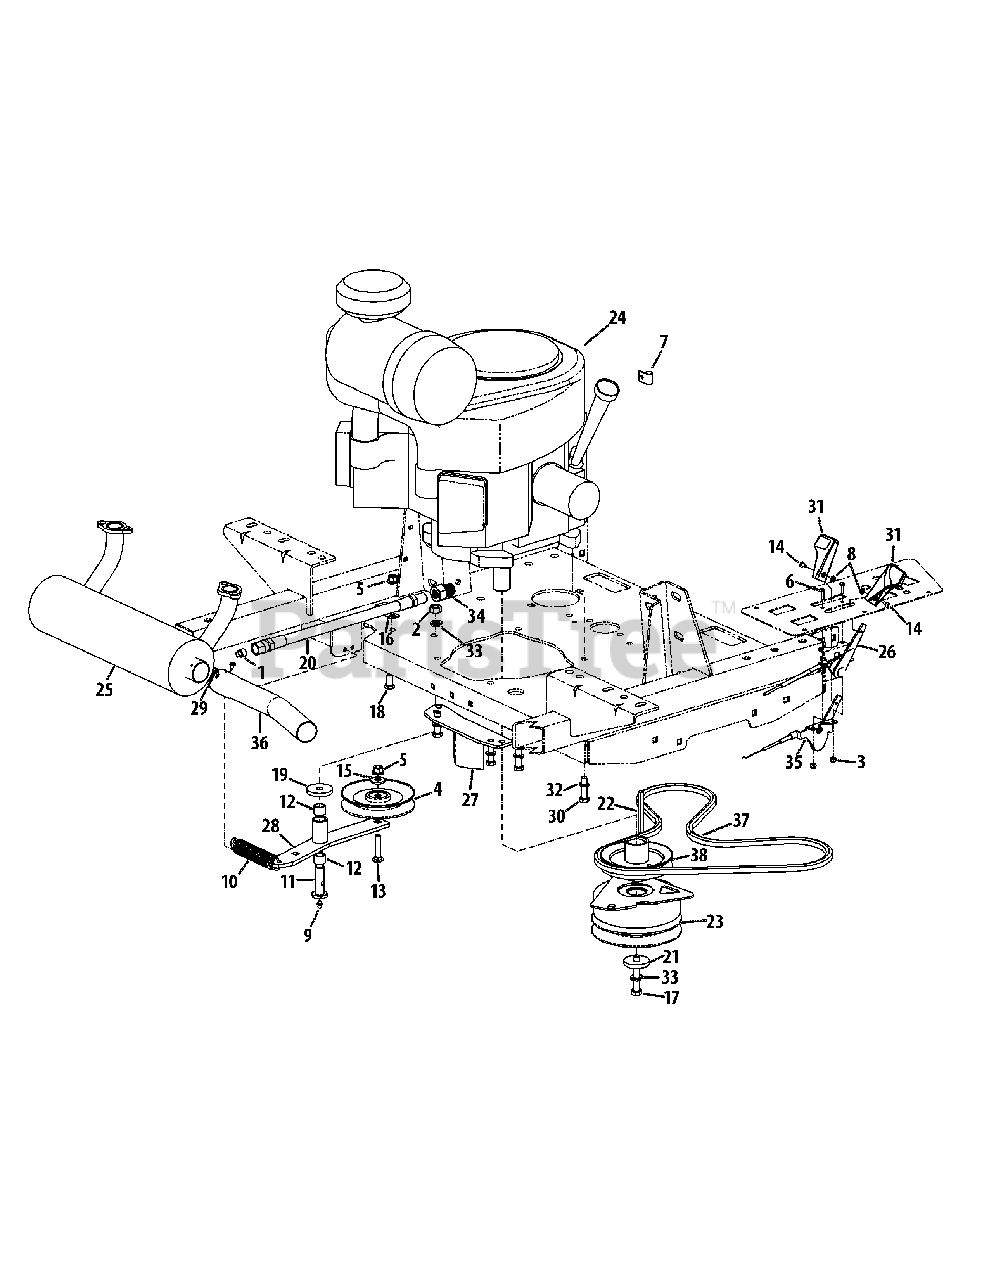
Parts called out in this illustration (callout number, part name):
1	Pipe Plug, 3/8
2	Nut, 7/16-14
3	Nut, #10-32
5	Flange Counter Lock Nut, 3/8-16
6	Machine Screw, #10-32 x .625
7	Clamp, 1/2
8	Nut, 8-32
9	Grease Fitting, 1/4-28
10	Extension Spring, 1.00 x 5.00 x .125
11	Shoulder Bolt, .625 x 1.95
12	Sleeve Bearing, .628 x.753 x .625
13	Carriage Bolt, 3/8-18 x 1.75
14	Machine Screw, #8-32 x .356
15	Washer, .406 x 1.00 x .105
16	Clip, .470 x 1.80
17	Hex Screw, 7/16-20 x 2.50
18	Hex Screw, 3/8-16 x .750
19	Washer, .438 x 1.75 x .250
20	Oil Drain Hose
21	Washer, .438 x 1.745 x .250
22	Key, .250 x .250 x 3.00
23	Brake Clutch
24	Kawasaki FX850V-AS00-S Engine
26	Choke Cable
27	Clutch Return Assembly
28	Idler Arm Assembly
29	Hex Washer Screw, #10-16 x 0.500
30	Hex Screw, 3/8-16 x 1.50
31	Throttle Control Knob
32	Lock Washer, 3/8
33	Lock Washer, 7/16
34	Fitting, 1.0
35	Throttle Cable
36	Exhaust Pipe
38	Drive Pulley
